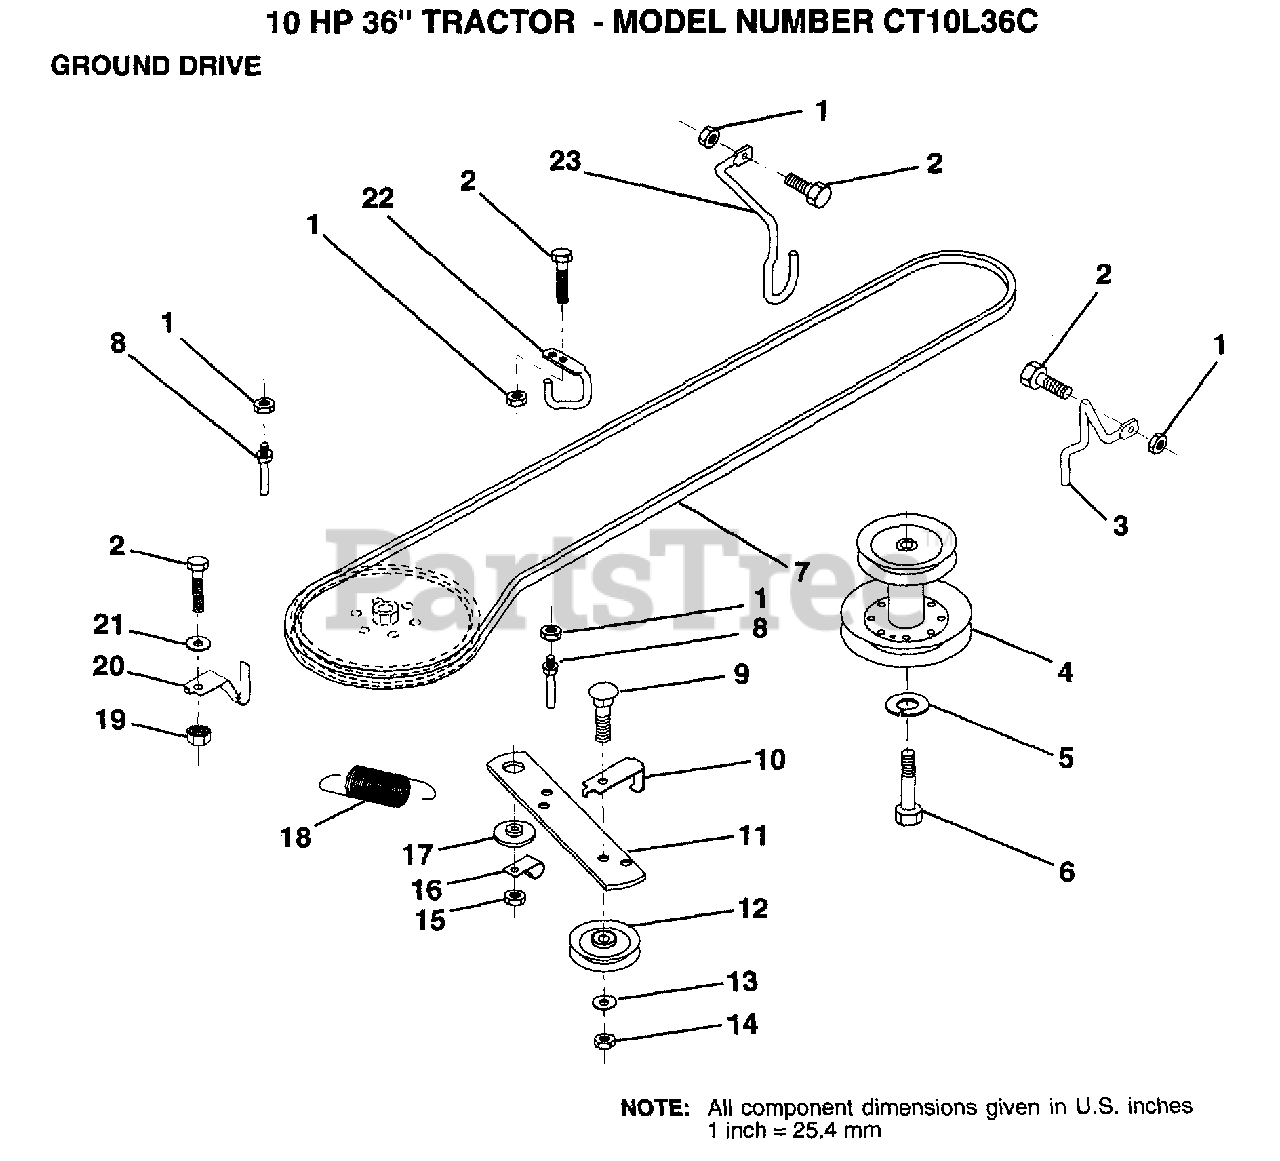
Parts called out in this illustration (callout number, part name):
1	NUT
2	BOLT
3	KEEPER RH
4	PULLEY.ENGINE.LR
5	LOCKWASHER
6	HEX BOLT
7	BELT
8	"KEEPER,DRIVE BELT"
9	BOLT
10	"KEEP,IDLER DR BEL"
11	ARM IDLER CLUT GD
12	PULLEY.IDLER.FLAT
13	WASHER
14	LOCKNUT
15	NUT
16	"CLIP,INSULATOR"
17	SPACER RETAINER
20	KEEPER.BELT.T/A
21	WASHER
22	"KEEPER,FRA DR BEL"
23	KEEPER MOWER LH
